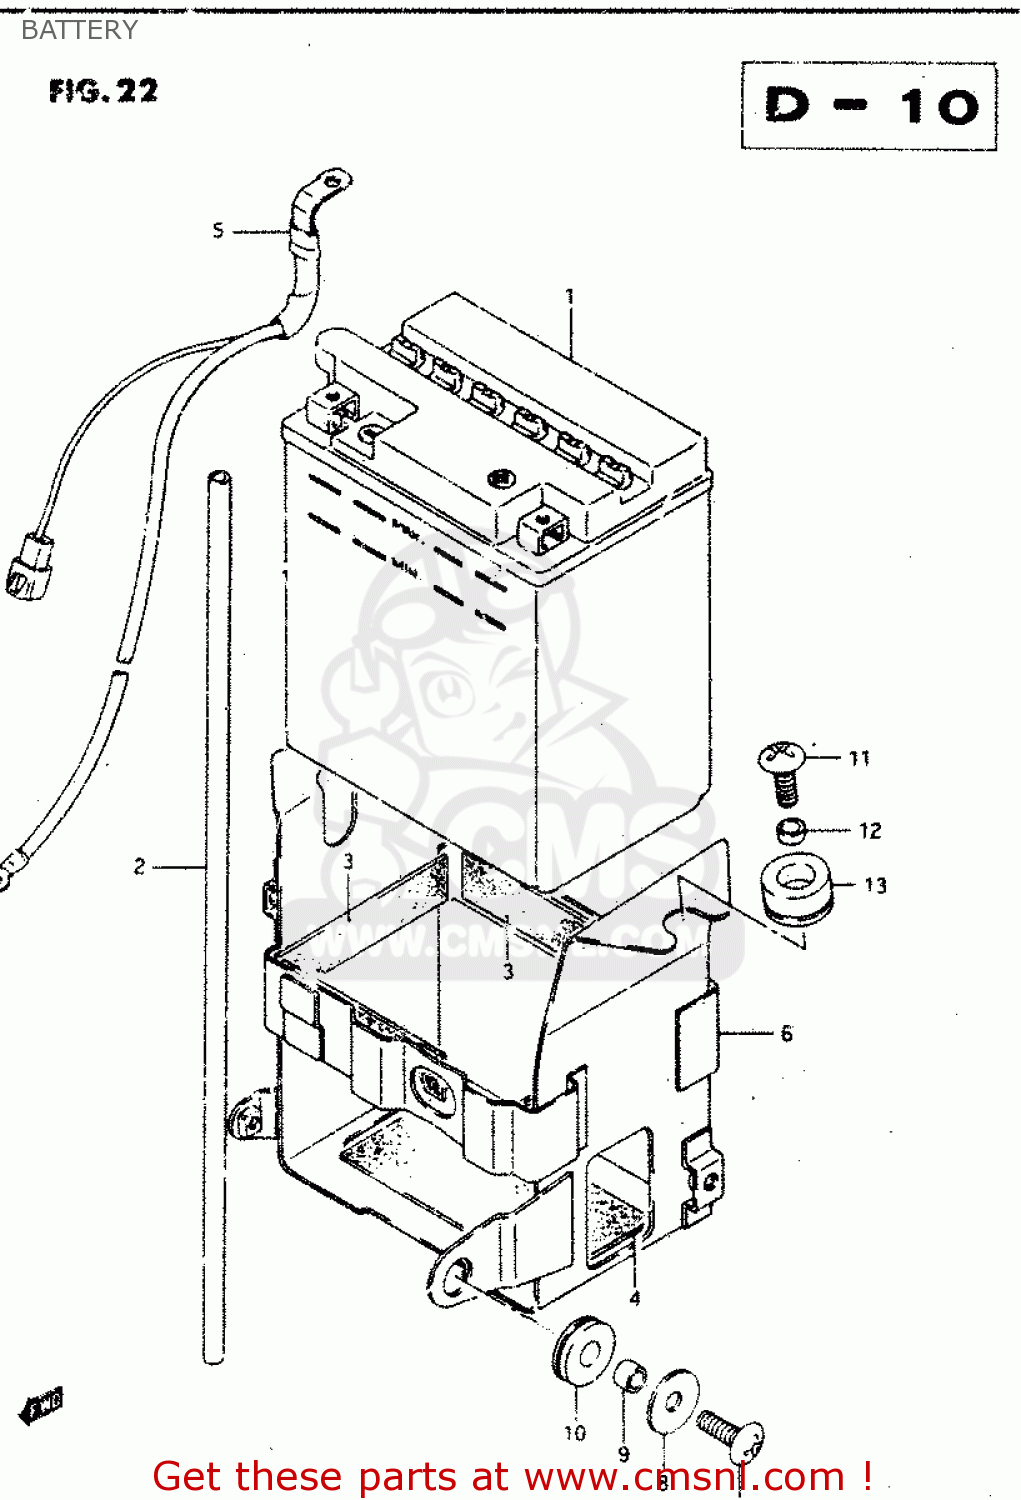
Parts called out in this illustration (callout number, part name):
1	BATTERY ASSY (12V)
2	HOSE,BATTERY EXHAUST
3	PROTECTOR,20X9
4	PROTECTOR(170X95X3.0)
5	WIRE,BATTERY MINUS LEAD
6	HOLDER,BATTERY
7	SCREW
8	WASHER (6.5X24X1.6)
9	SPACER
10	CUSHION
11	SCREW
12	SPACER
13	CUSHION,BATTERY HOLDER
